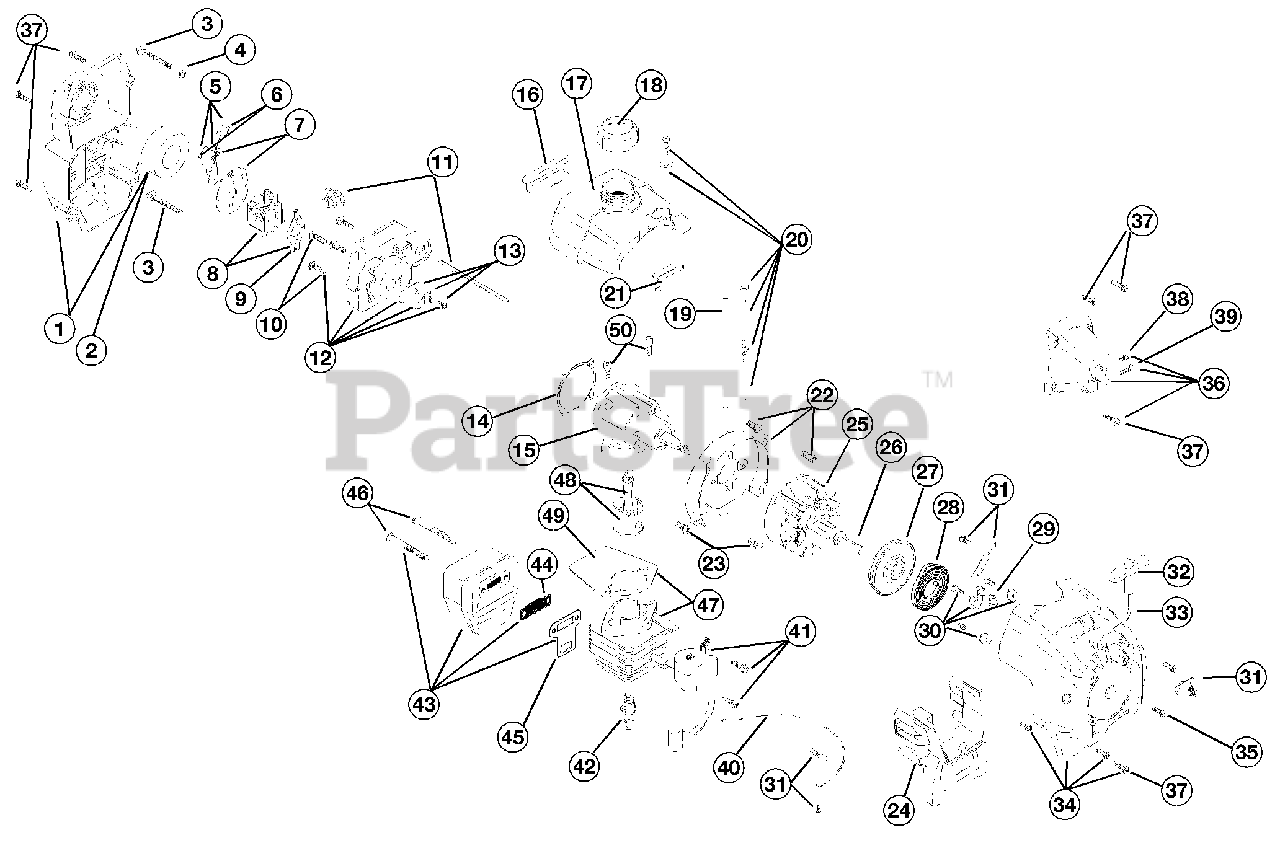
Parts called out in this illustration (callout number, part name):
1	Air Cleaner/Muffler Cover Assembly
2	Air Cleaner Filter
3	Carburetor Mounting Screw Assembly
4	Wavey Washer
5	Choke Lever Assembly
6	Choke Knob and Screw
7	Choke Lever and Plate
8	Carburetor Assembly
9	Carburetor Gasket
10	Carb Mount Screw
11	Primer and Hose Assembly
12	Carb Mount Assembly
13	Reed Assembly
14	Carburetor Mount Gasket
15	Crank Case Service Assembly
16	Rear Mounting Pad
17	Fuel Tank Assembly
18	Fuel Cap Assembly
19	Fuel Return Line
20	Fuel Line Assembly
21	Front Mounting Pad
22	Shroud Assembly
23	Shroud Screw
24	Shroud Extension & Stand
25	Flywheel Assembly
27	Recoil Pulley Assembly
28	Recoil Spring
29	Rope Guide
30	Pulley Retainer Assembly
31	Switch Assembly
32	Pull Handle
34	Starter Housing Assembly
35	Housing Screw
36	Clutch Cover Assembly
37	Cover Screw
38	Anti-Rotation Screw
39	Clamping Screw
40	Wire Lead
41	Module Assembly
42	Spark Plug
43	Muffler Assembly
44	Spark Arrestor Screen
45	Exhaust Gasket
46	Muffler Mounting Bolt Assembly
47	Cylinder Assembly
48	Piston and Rod Assembly
49	Cylinder Gasket
50	Cylinder Bolt
